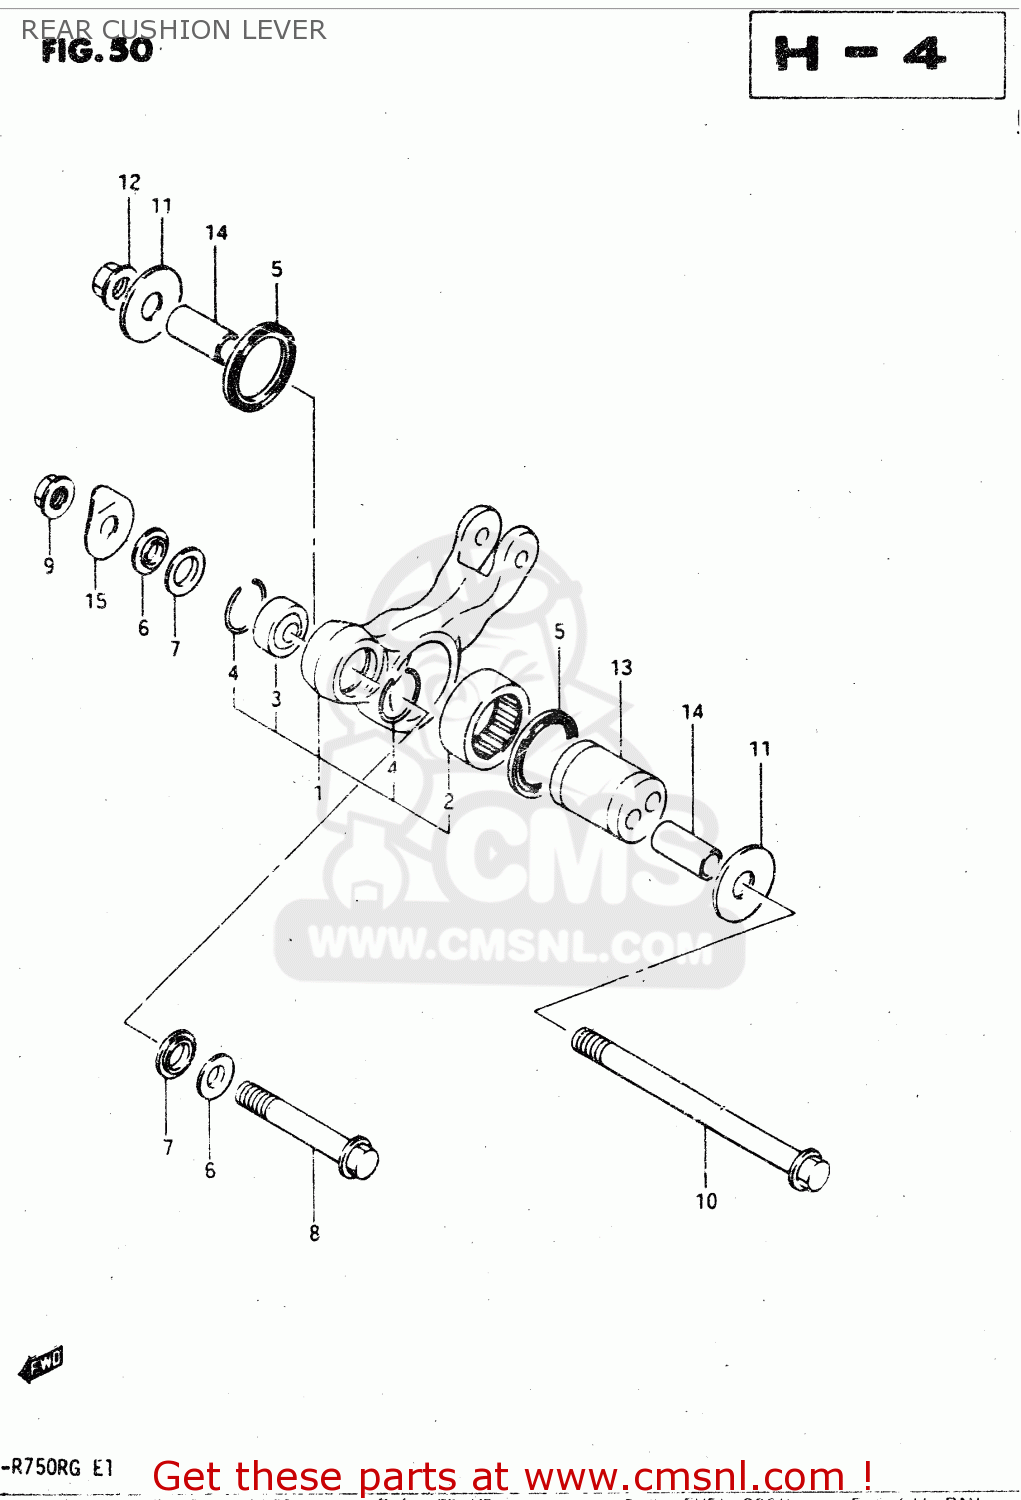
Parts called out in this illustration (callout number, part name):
1	LEVER SET,REAR CUSHION
2	BEARING(35X45X20)
3	BEARING(12X26X16)
4	RING,STOPPER
5	SEAL,INNER DUST
6	SPACER,RR CUSHION ROD
7	SEAL,RR CUSHION ROD DUST
8	BOLT,RR CUSHION LEVER FR
9	NUT 12MM
10	SHAFT
11	WASHER
12	NUT 12MM
13	SPACER,REAR CUSHION ECCENTRIC
14	SPACER
15	SHIM,REAR CUSHION LEVER
